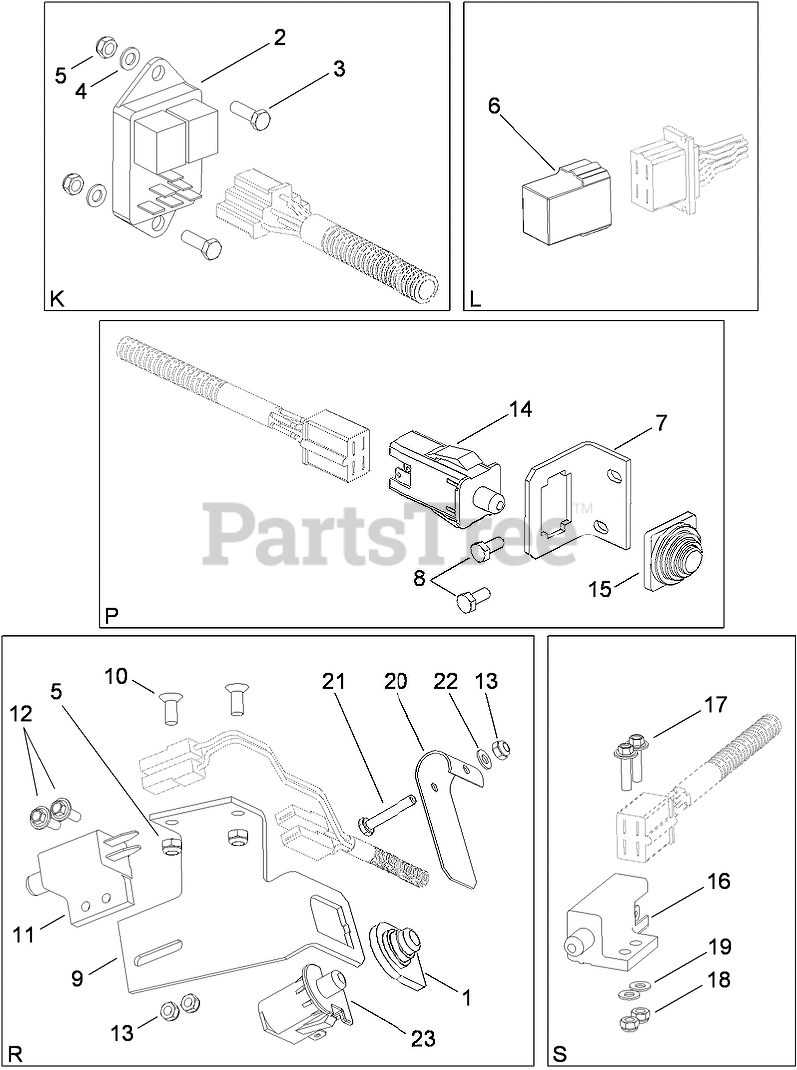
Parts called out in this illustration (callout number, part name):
1	COVER-PROTECTIVE
2	MODULE-CLUTCH
3	SCREW-HH
4	WASHER
5	NUT-LOCK
6	CIRCUIT-MEMORY
7	Holder-Switch
9	Holder-Switch
11	SWITCH-POLE, SINGLE
13	NUT-HEX
14	Switch-Delta
15	Cover-Switch
16	Switch-Delta
18	NUT-LOCK
19	WASHER
20	Lever-Spring
21	SCREW-HEX
22	Washer
23	SWITCH-DELTA
